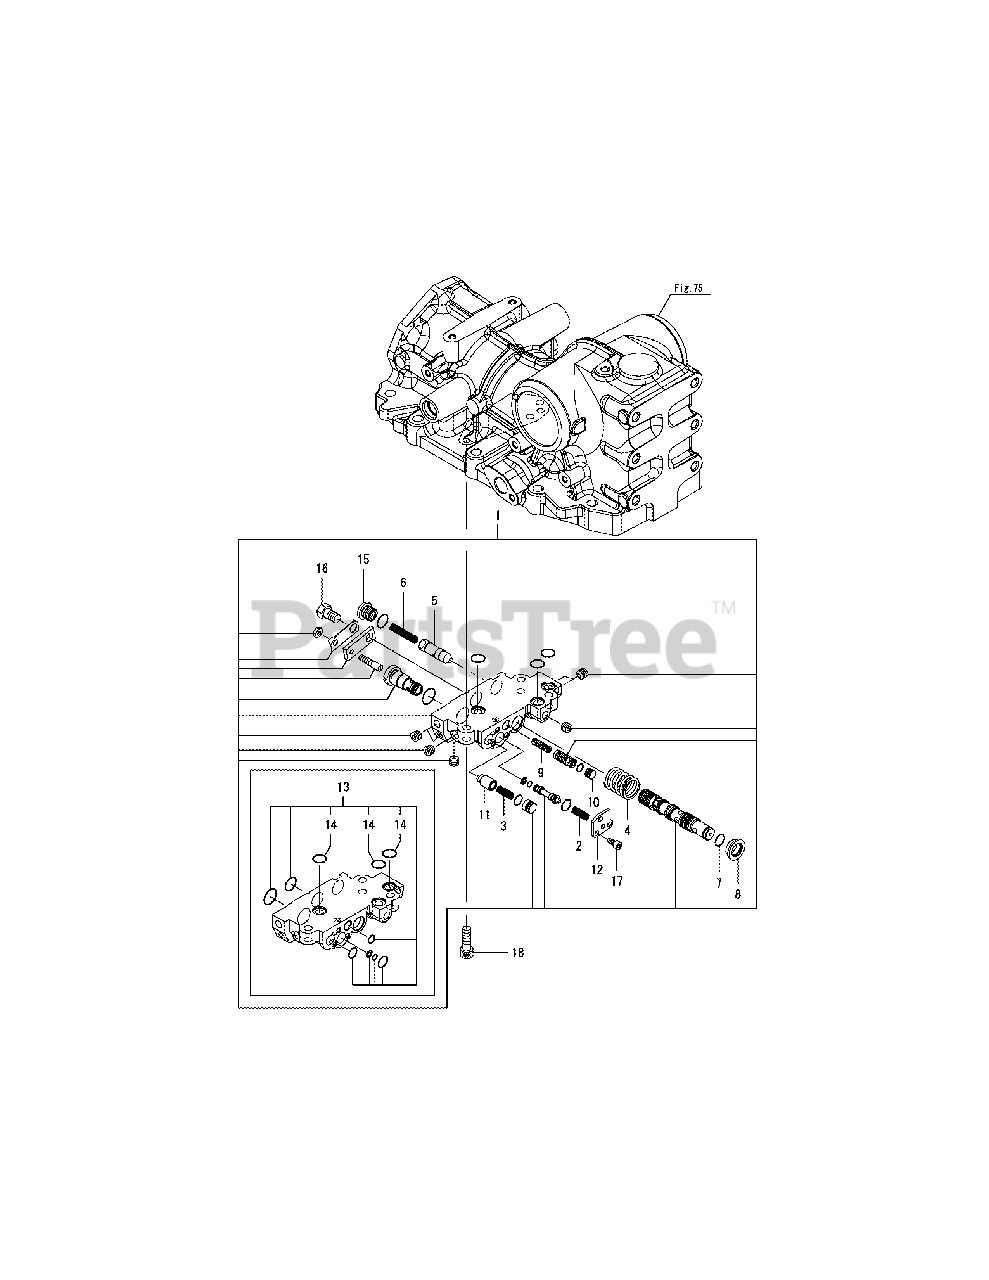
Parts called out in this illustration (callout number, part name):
1	VALVE ASSY, CONTROL
5	POPPET, UNLOAD
7	RING, WIRY SNAP
13	SEAL KIT, VALVE
15	PLUG,LIFT VALVE
16	BOLT M10X 16 PLATED
